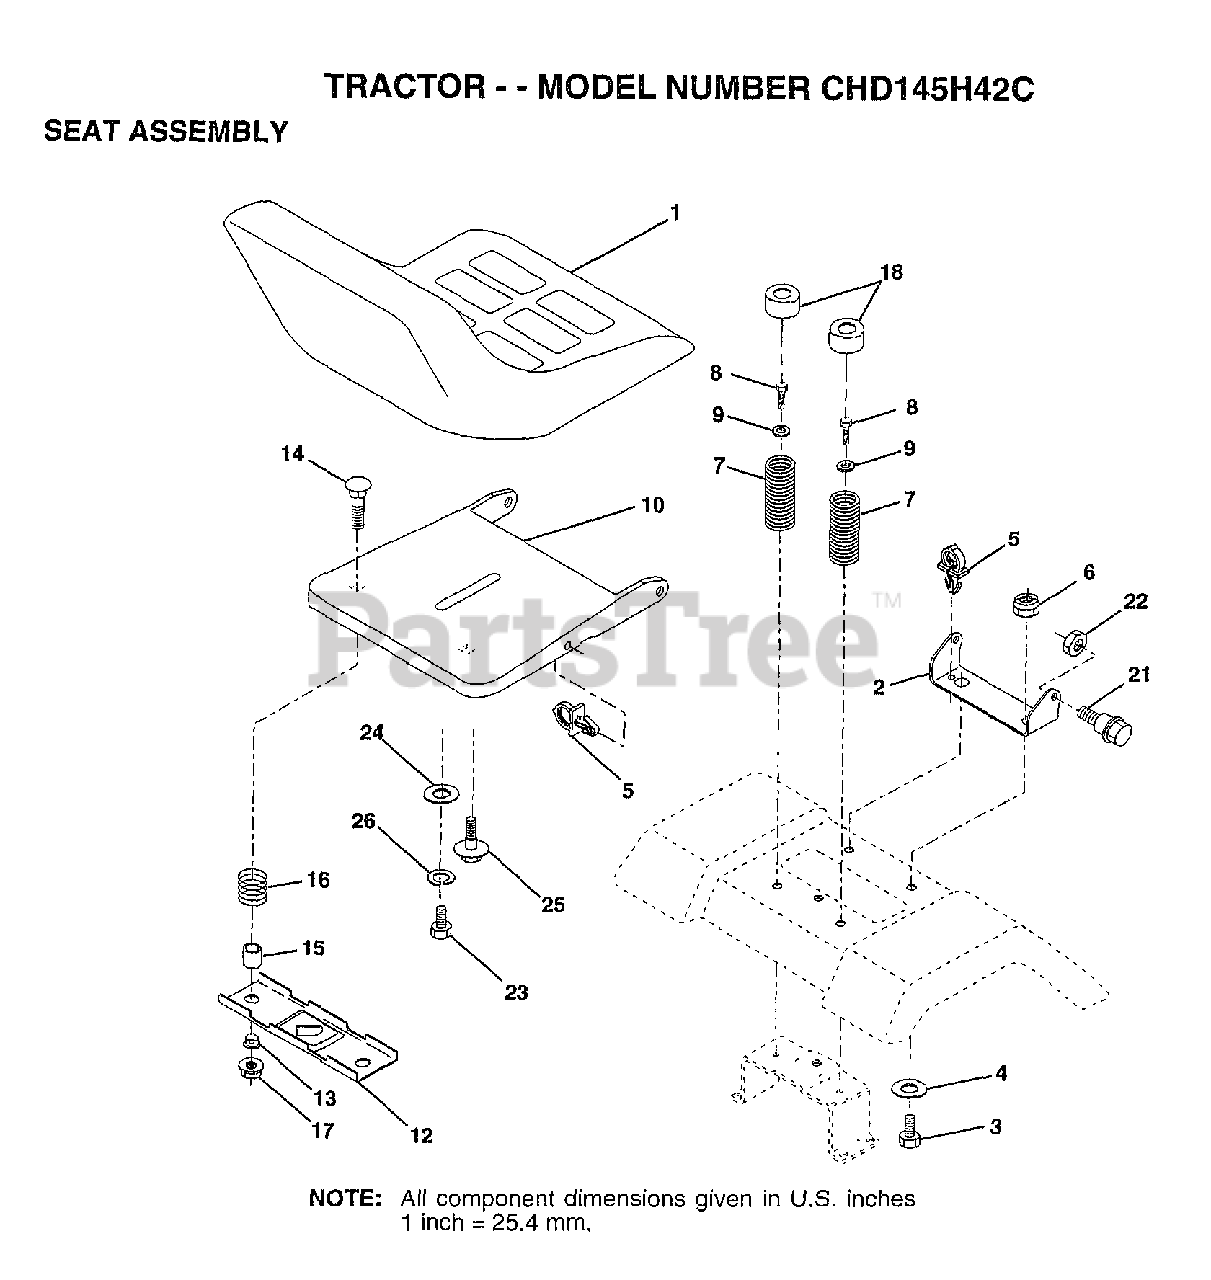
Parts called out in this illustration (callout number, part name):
1	SEAT
2	BRACKET PVT SEAT
3	BOLT
4	WASHER PM
5	CLIP.PUSH-IN.HING
6	NUT
7	SPRING COMPRESSIO
8	SCREW GTV
9	WASHER
10	PAN-SEAT
12	BRKT SWITCH
13	BUSHING
14	BOLT-RD HD SQ NK
15	SPLIT SPACER
16	SPRING
18	CAP SPRING
21	"BOLT,SHOULDER"
22	NUT
23	BOLT
24	WASHER
25	"BOLT,SHOULDER"
26	LOCKWASHER
